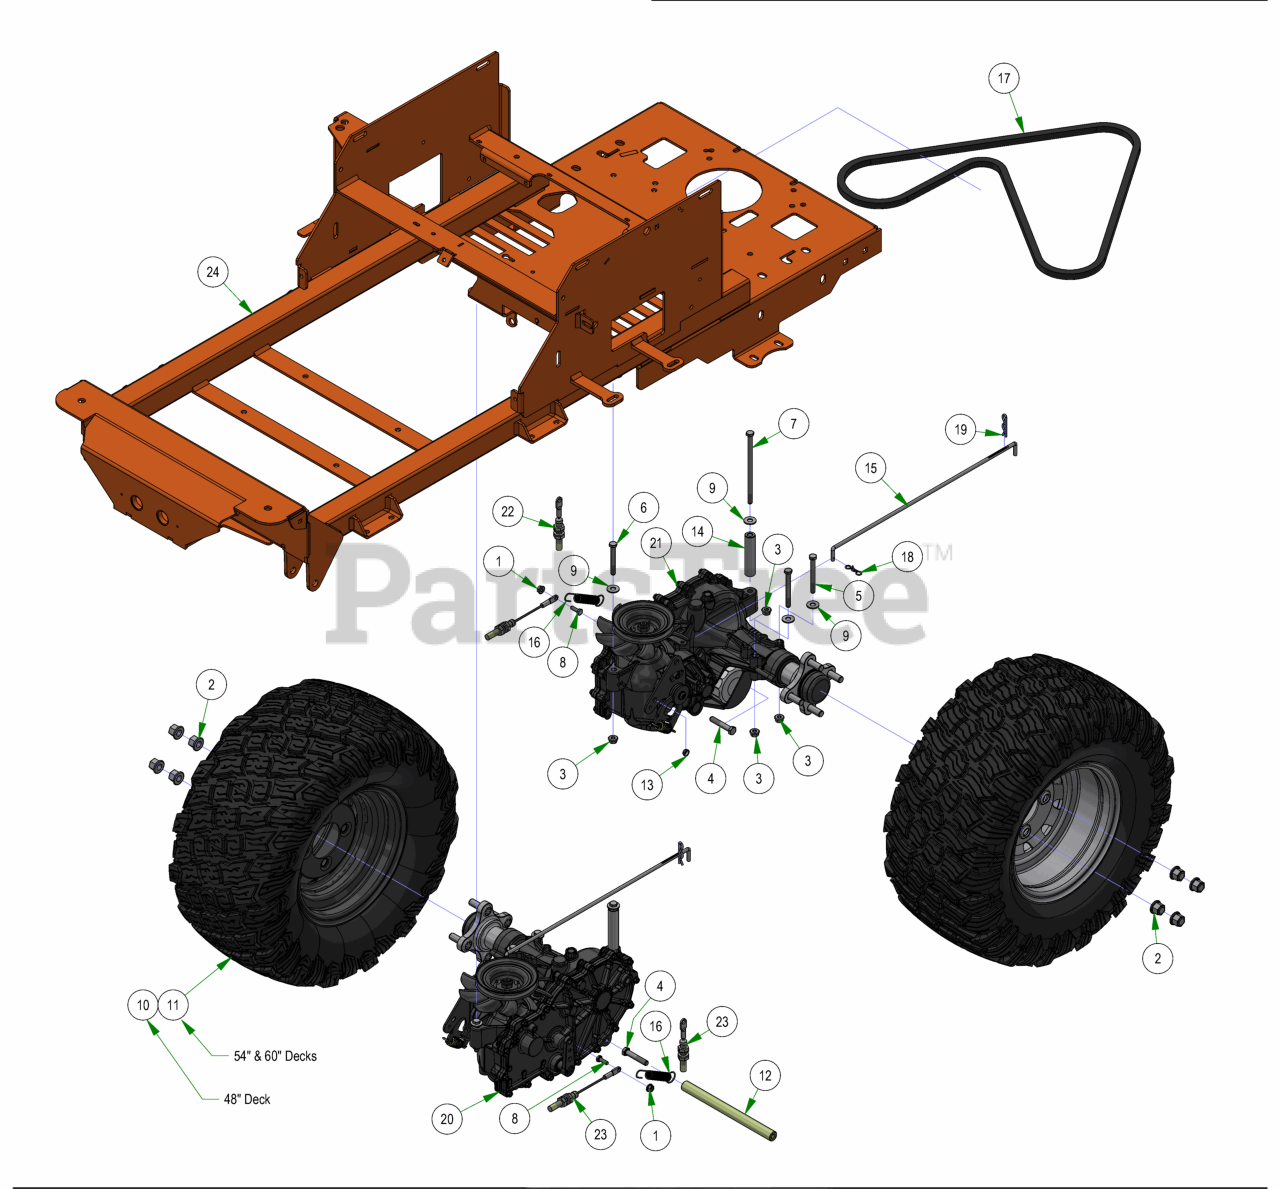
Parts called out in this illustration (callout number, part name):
1	1/4-20 NYL INSERT FLANGE LOCKNUT ZINC
2	Acorn Lug Nut
3	5/16-18 NYLON INSERT FLANGE LOCKNUT ZINC
4	3/8-16 X 2 HEX CAP SCREW (GR.5) ZINC
5	5/16-18 X 3 HEX CAP SCREW (GR.5) ZINC
6	5/16-18 X 2-1/2 HEX CAP SCREW (GR.5) ZINC
7	5/16-18 X 6 HEX CAP SCREW (GR.5) ZINC
8	1/4-20 X 3/4 HEX CAP SCREW (GR.5) ZINC
9	5/16 USS FLAT WASHER (7/8 OD) ZINC
10	22-10x10 Reaper Wheel/Tire Assembly
11	22x11-10 Reaper Rear Black Assembly
12	2017 Transaxle Spacer-ZT
13	Drive Arm Transaxle Spacer
14	2017 Transaxle Spacer
15	Neutral Rod
16	Brake Return Spring
19	Neutral Rod Clip
20	2025 RH 3100 Transaxle
21	2025 LH 3100 Transaxle
22	2021 Load Balanced Brake Cable 1
23	2021 Load Balanced Brake Cable 2
24	2025 ZT Elite Frame
